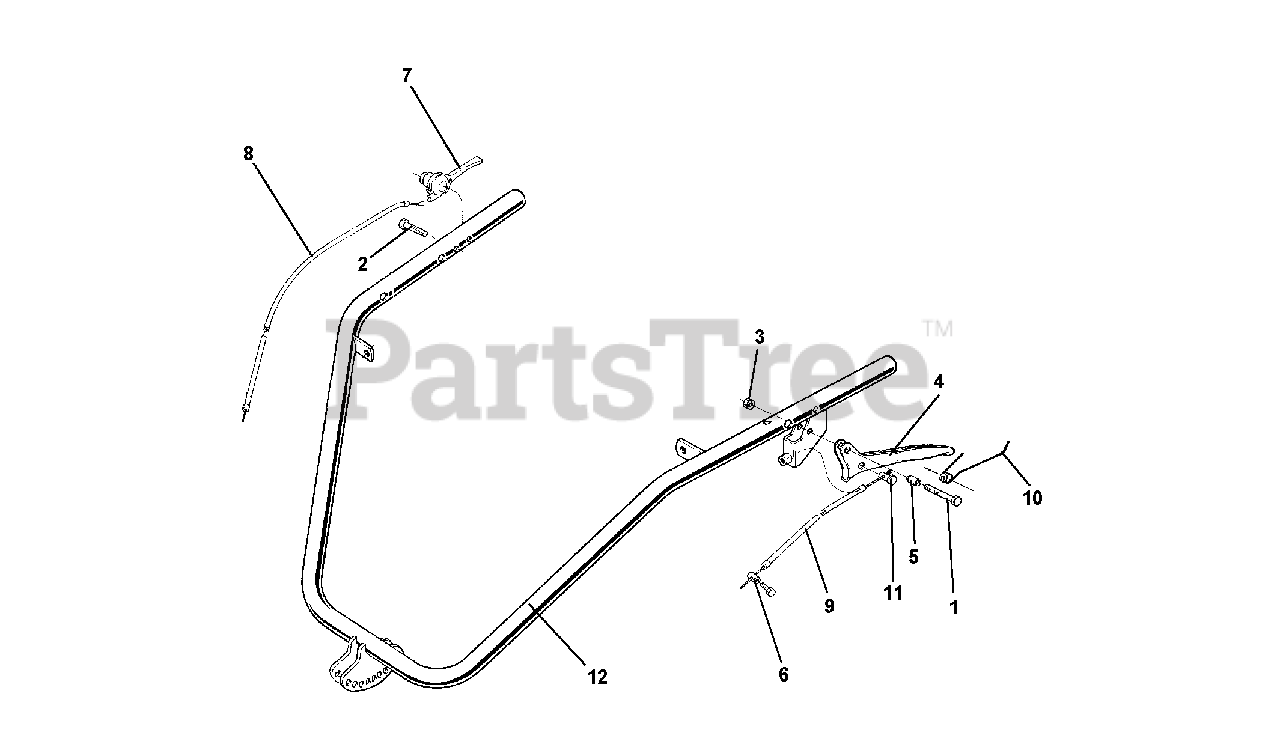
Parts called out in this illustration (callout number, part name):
1	SCREW M6 X 25
2	SCREW M6 X 40
3	NUT, SELF LOCKING M6
5	LEVER SPACER
6	CLAMP, CABLE
7	LEVER, ACCELERATOR
8	CABLE & SHEATH, ACCEL.LOMBARCABLE VAINA GAS LOMBARDINI
9	WIRE & SHEATH L 930 DISENG.
10	LEVER SPRING
